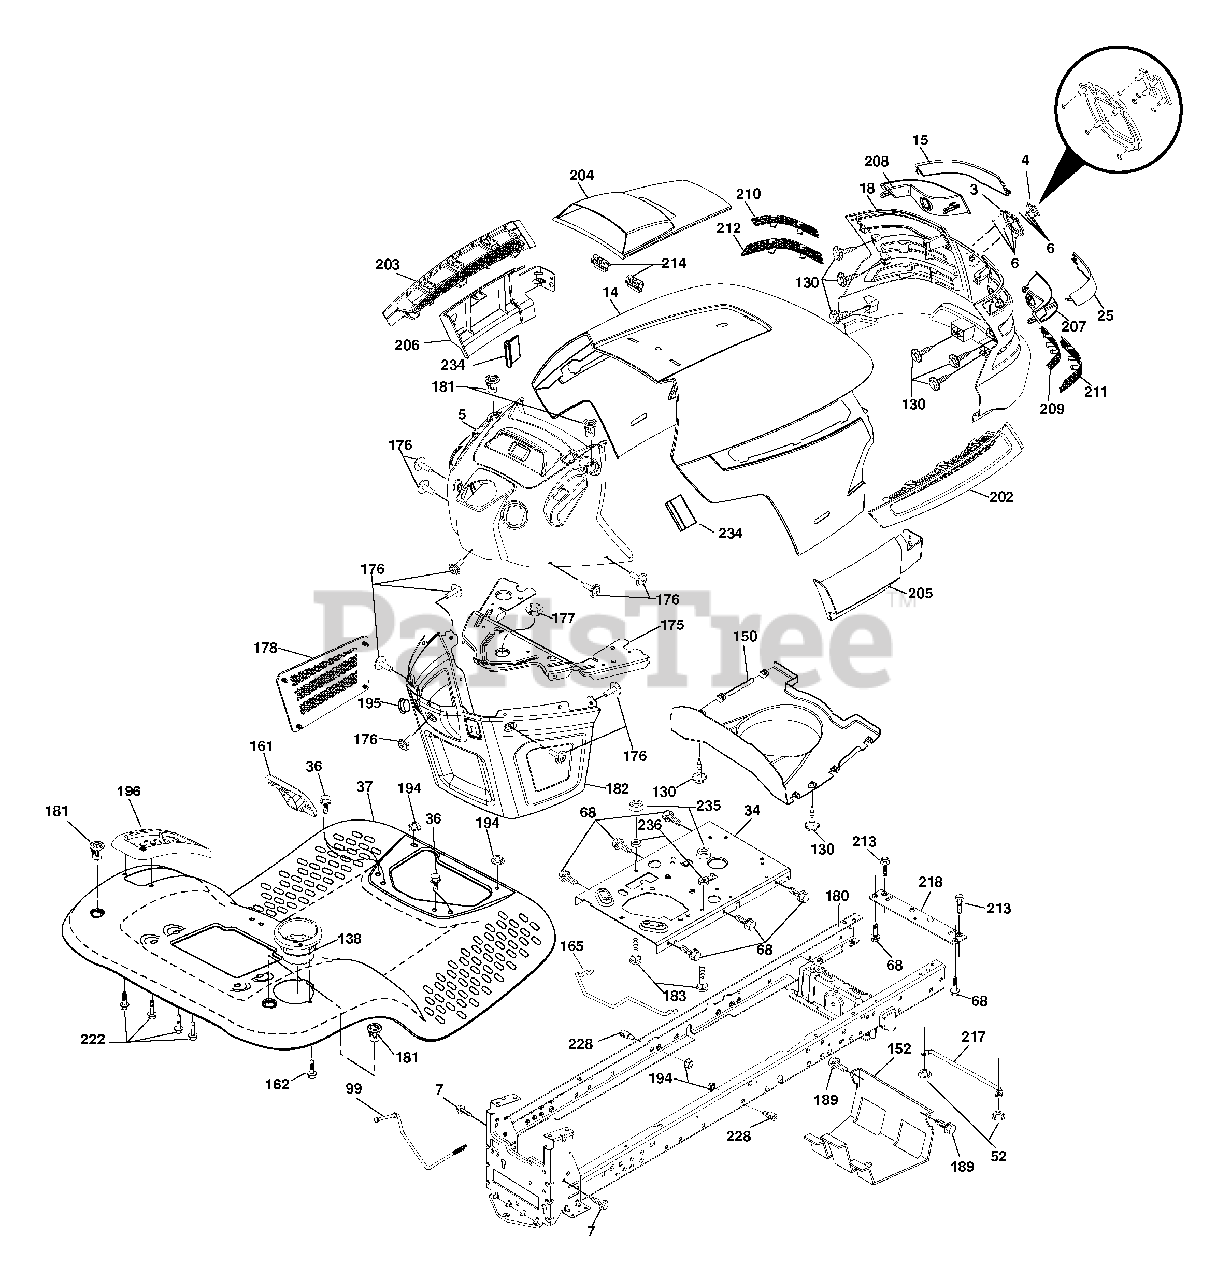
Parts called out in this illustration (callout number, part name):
3	Logo Crown
4	Logo
7	Bolt Shoulder
14	Hood
18	Grille Asm.
34	Plate Engine
36	Screw 5/16-18 x 3/4
37	Fender
52	Nut Lock 5/16-18
68	Screw 5/16-18 x 1/2
99	Rod Asm Bypass
130	Screw 10 x 3/4 Single Lead-Hex
138	Cupholder
152	Shield Browning
161	Window Fuel
165	Support Tank Rear
175	Crossmember
176	Screw 10-24 x 5/8
177	Bushing Steering
178	Cargo Net Asm.
180	Chassis
181	Bushing Mtg. Fender Crgo
182	Dash Lower
183	Bolt Fin Hex 5/16-18 unc x 1-1/4
189	Screw 5/16-18 x 3/4
194	Nut Lock Hex Flange 5/16-18
195	Plug Hole Dash Lower
196	Console Asm. Deck Lift
202	Vent Side Hood RH
203	Vent Side Hood LH
204	Vent Top Hood
205	Skirt Hood Side RH
206	Skirt Hood Side LH
209	Insert Hex Top RH
210	Insert Hex Top Lh
211	Insert Hex Bottom RH
212	Insert Hex Bottom LH
213	Bolt 5/16-18 UNC x 3/4
214	Clip Retainer Tinner
217	Rod Pivot
218	X-Piece Hood Stop
222	Screw Thdrol 1/4-20 x 5/8
228	Stud Fastner
234	Bumper Hood
235	Spacer Fender
236	Nut Lock 5/16-18 UNC
